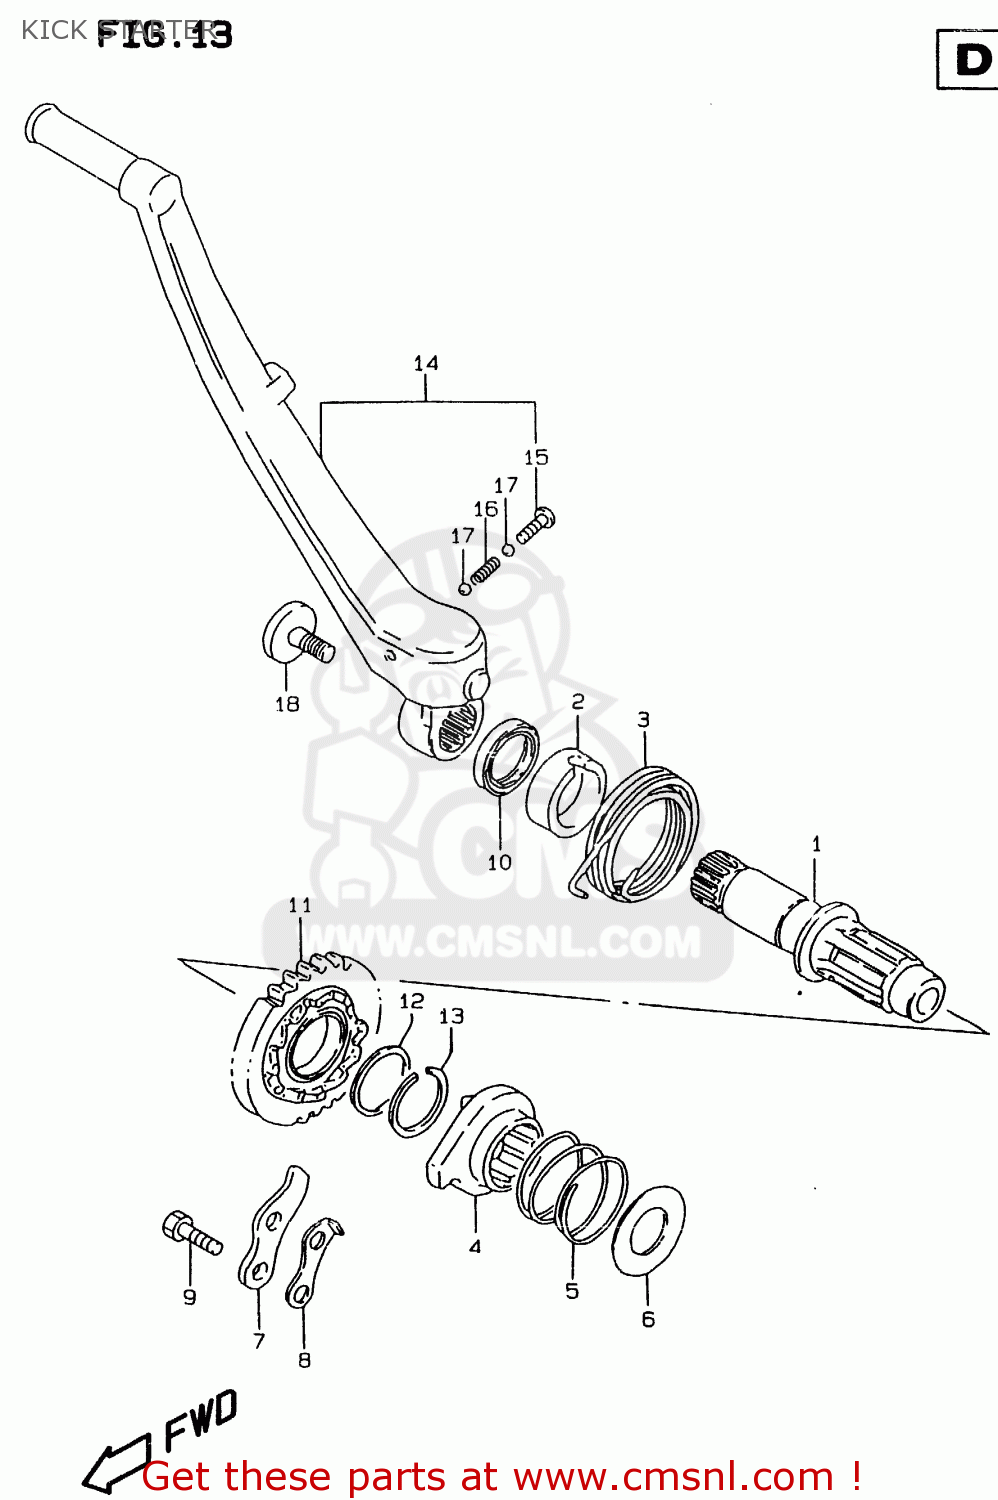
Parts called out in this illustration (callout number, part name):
1	SHAFT,KICK STARTER
2	GUIDE,KICK STARTER SHAFT
3	SPRING
4	STARTER,KICK
5	SPRING
6	WASHER
7	GUIDE,KICK STARTER
8	STOPPER,KICK STARTER
9	BOLT
10	SEAL,OIL(20X27X5)
11	GEAR,KICK STARTER DRIVE(NT:30)
12	SHIM(22X28X1)
13	CIRCLIP
14	LEVER ASSY,KICK STARTER
15	SCREW(6X27.5)
16	SPRING
17	BALL
18	BOLT(8X14)
